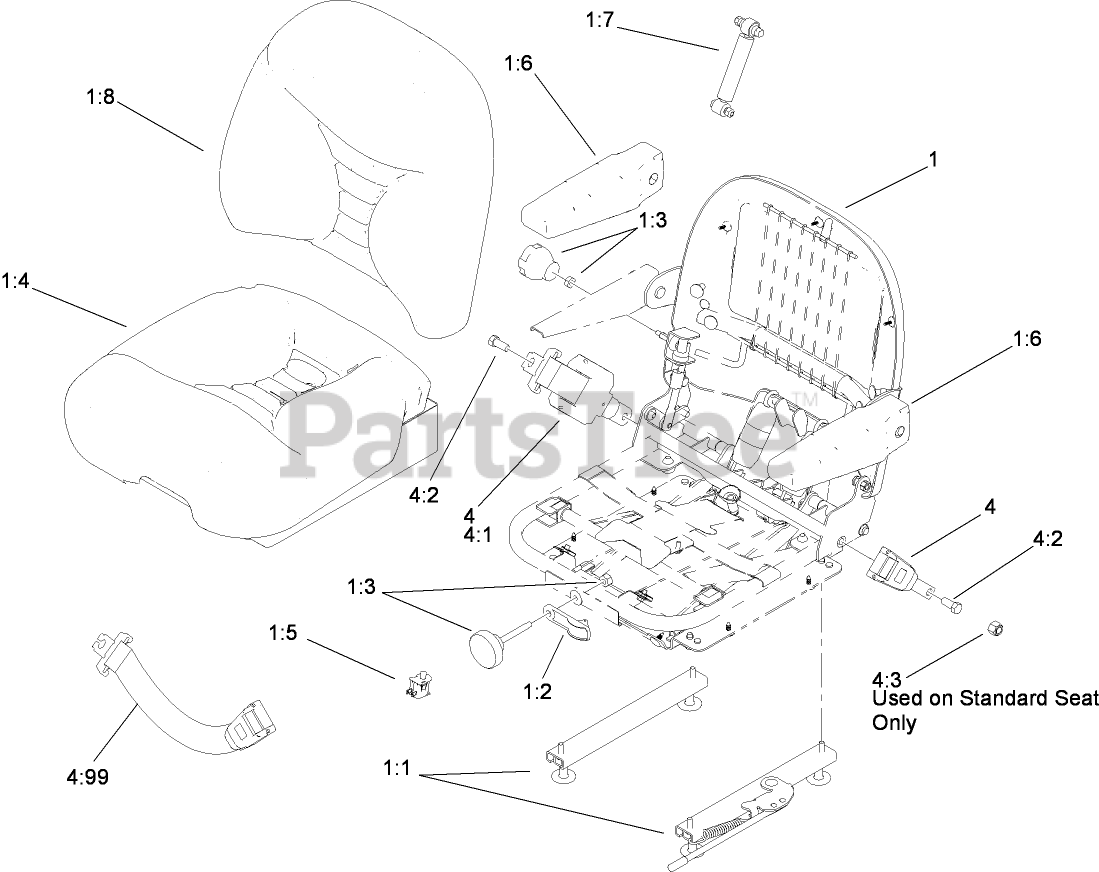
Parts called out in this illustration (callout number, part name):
1	SEAT-SUSPENSION
1:1	Seat Track Kit
1:2	Weight Indicator Kit
1:3	Knob Kit
1:4	Bottom Cushion Kit
1:5	SWITCH-BAIL
1:6	PAD-ARMREST
1:7	Shock Absorber Kit
1:8	CUSHION-BACK
4	RETRACTABLE SEATBELT KIT
4:1	SEATBELT-RETRACTABLE
4:2	SCREW-HH
4:3	NUT-LOCK
4:99	SEAT BELT EXTENSION KIT
